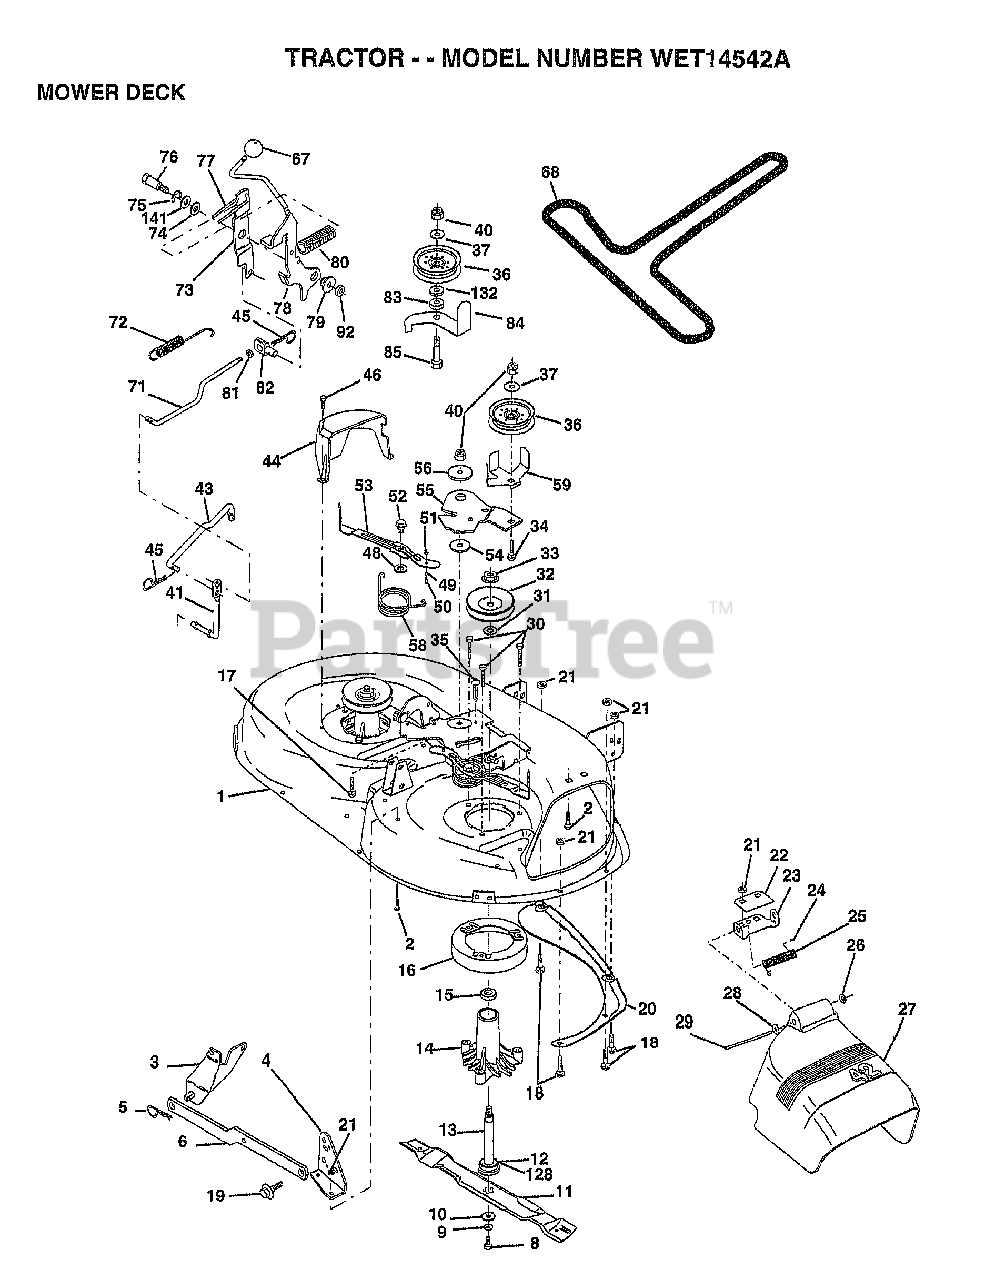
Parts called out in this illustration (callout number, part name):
1	"HOUSING ASSY.42"""
2	BOLT
3	BRKT ASM SWAY BAR
4	BRKT DECK SW BAR
8	BLADE BOLT
10	WASHER.HARD.BLADE
11	"BLADE.42"" HIPERF"
12	BEARING.BALL
14	HSG ASM MANDREL
15	BEARING
16	STRIPPER RND MWR
17	BOLT RDHD 3/8-16
18	BOLT
19	BOLT SHD 5/16-18
20	BAFFLE VORTEX 42
22	STIFFENER BRKT
23	DEFLECTOR BRKT
24	CAP-SLEEVE LT
25	SPRING TORSION
26	NUT PUSH M
27	DEFLECTOR.SHIELD
28	WASHER
29	HINGE ROD
30	"SCREW-THD ROLL,WA"
31	WASHER
32	PULLEY.MANDREL.42
34	BOLT
35	XMAS TREE FASTNER
36	FLAT IDLER PULLEY
37	WASHER
41	PIVOT ROD
43	ROD CLUTCH W/NIBS
44	GUARD MAND LH BLK
45	RETAINER M
46	SCREW.1/4-20X5/8
48	HARD SMALL WASHER
49	ROLLER ASM-CAM
50	SHOULDER BOLT
51	LOCKNUT
52	BOLT.SHLD.5/16-18
53	BRAKE PAD ARM ASM
54	HARDENED WASHER
55	ARM-IDLER
56	SPACER RETAINER
58	SPRING TORSN BRAK
59	GUARD IDLER TUV
67	KNOB.RD.7/16-14
68	BELT.V.T-PATH
71	ROD CLUTCH 38/42
72	RETURN SPRING
73	CLUTCH ARM SECOND
74	WASHER
75	RING
76	SHOULDER BOLT
77	SPRING KEEPER
78	LEVER.ASM.CLUTCH
79	BUSHING
80	SPRING.CLUTCH.MWR
81	NUT
82	TRUNION ADJ
83	WASHER
84	"KEEPER-BELT,FIXED"
85	BOLT
92	NUT
128	WASHER.FELT.
132	WASHER GT
141	WASHER .T
